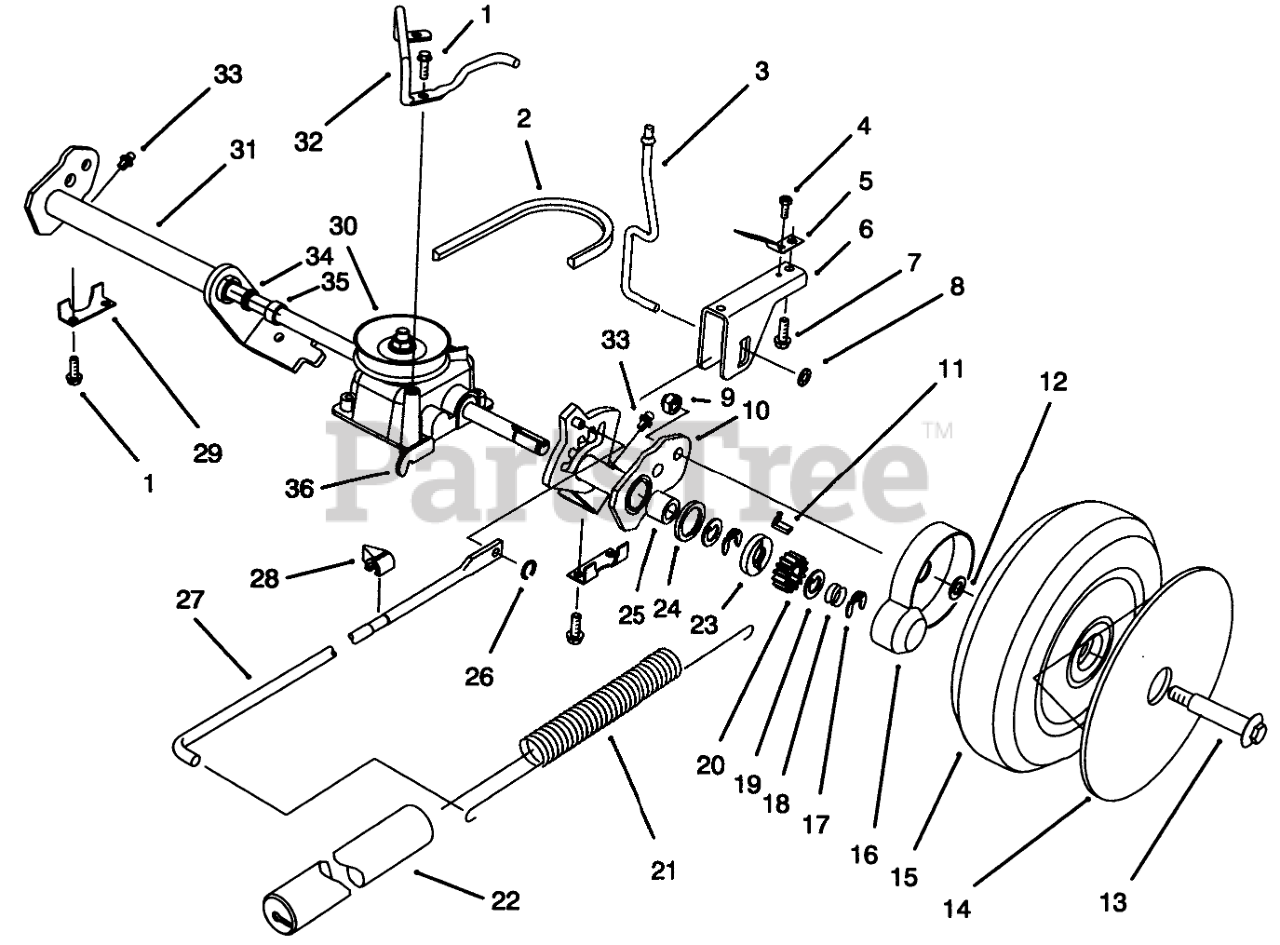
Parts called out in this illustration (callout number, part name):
1	SCREW-HWH
2	V-BELT
3	TRIGGER ROD
4	SCREW 8 - 32 X 250
5	SPRING - TRIGGER RET
6	SADDLE - HOC
7	SCREW
8	PUSHNUT
9	NUT-HEX
10	Arm-Pivot L.H. (Incl. Ref. #25, & 33-35)
11	KEY-ROCKING, LH
12	SPACER-COVER, WHEEL
13	BOLT-WHEEL
14	COVER-WHEEL
15	WHL & TIRE ASSEMBLY
16	COVER-WHEEL
17	RING-CLIP, LOCKING
18	SPRING-COMPRESSION
19	WASHER-THRUST, KEYED
20	GEAR-PINION
21	SPRING-COUNTERBALANCE
22	COVER-SPRING
23	WASHER-CLUTCH
24	RING-FRICTION
25	BEARING-ROLLER
26	GRIP RING
27	LINK ROD
28	INDICATOR-HEIGHT OF CUT
29	REAR SECURING PLATE
30	GEAR CASE ASSY
31	Arm-Pivot R.H. (Incl. Ref. #25, & 33-35)
32	Retainer Belt
33	FITTING-GREASE
34	SEAL-OIL
35	BUSHING
36	Bracket-Traction
